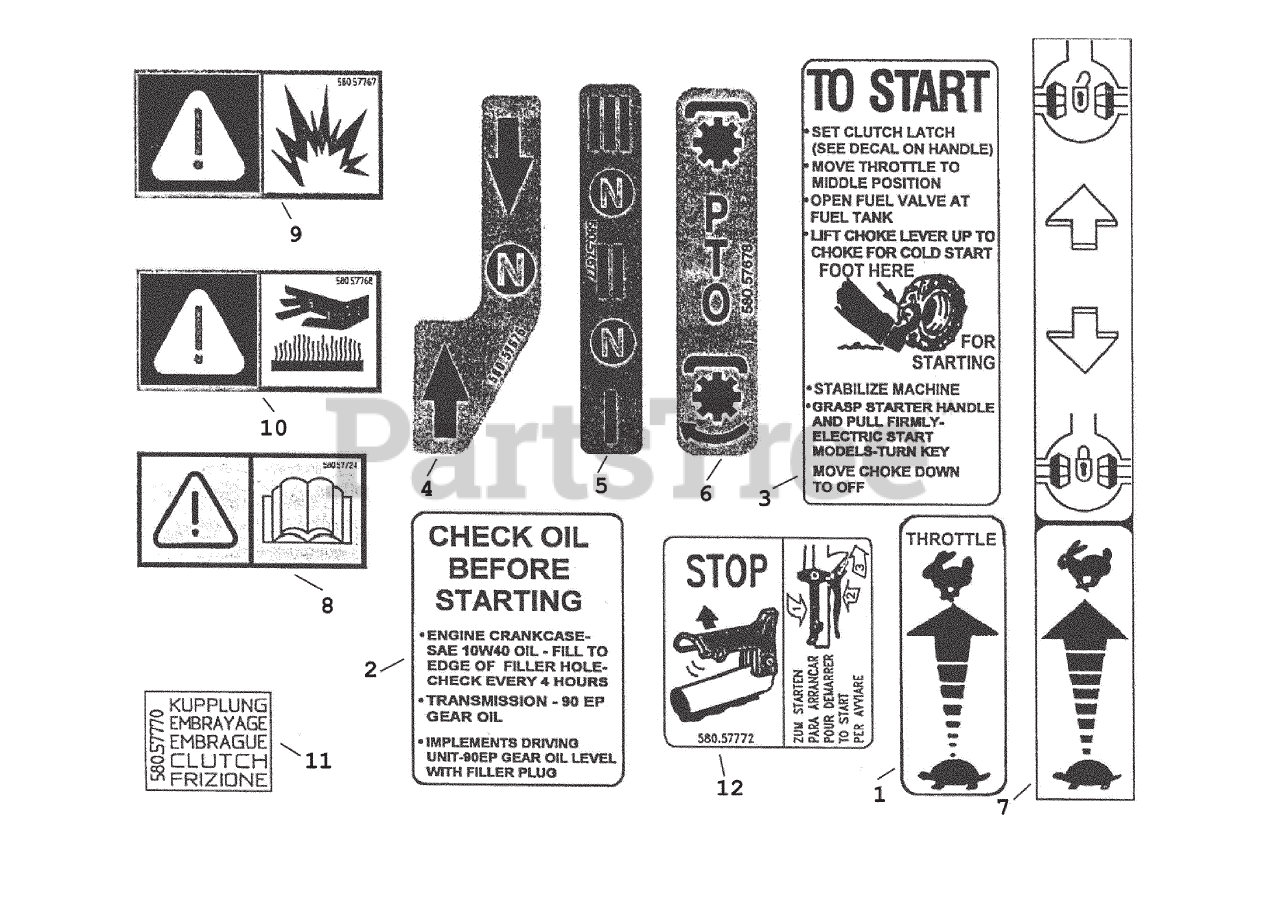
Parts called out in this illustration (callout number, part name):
1	DECAL, THROTTLE
2	DECAL, CHECK OIL
3	DECAL, TO START
4	DECAL, NEUTRAL
5	DECAL, GEAR
6	DECAL, PTO
7	DECAL, DIFF & THROTTLE
8	DECAL, READ OP MANUAL
9	DECAL, GEAR
10	DECAL, PTO
11	DECAL, CLUTCH
12	DECAL, OPERATOR PRESENCE
